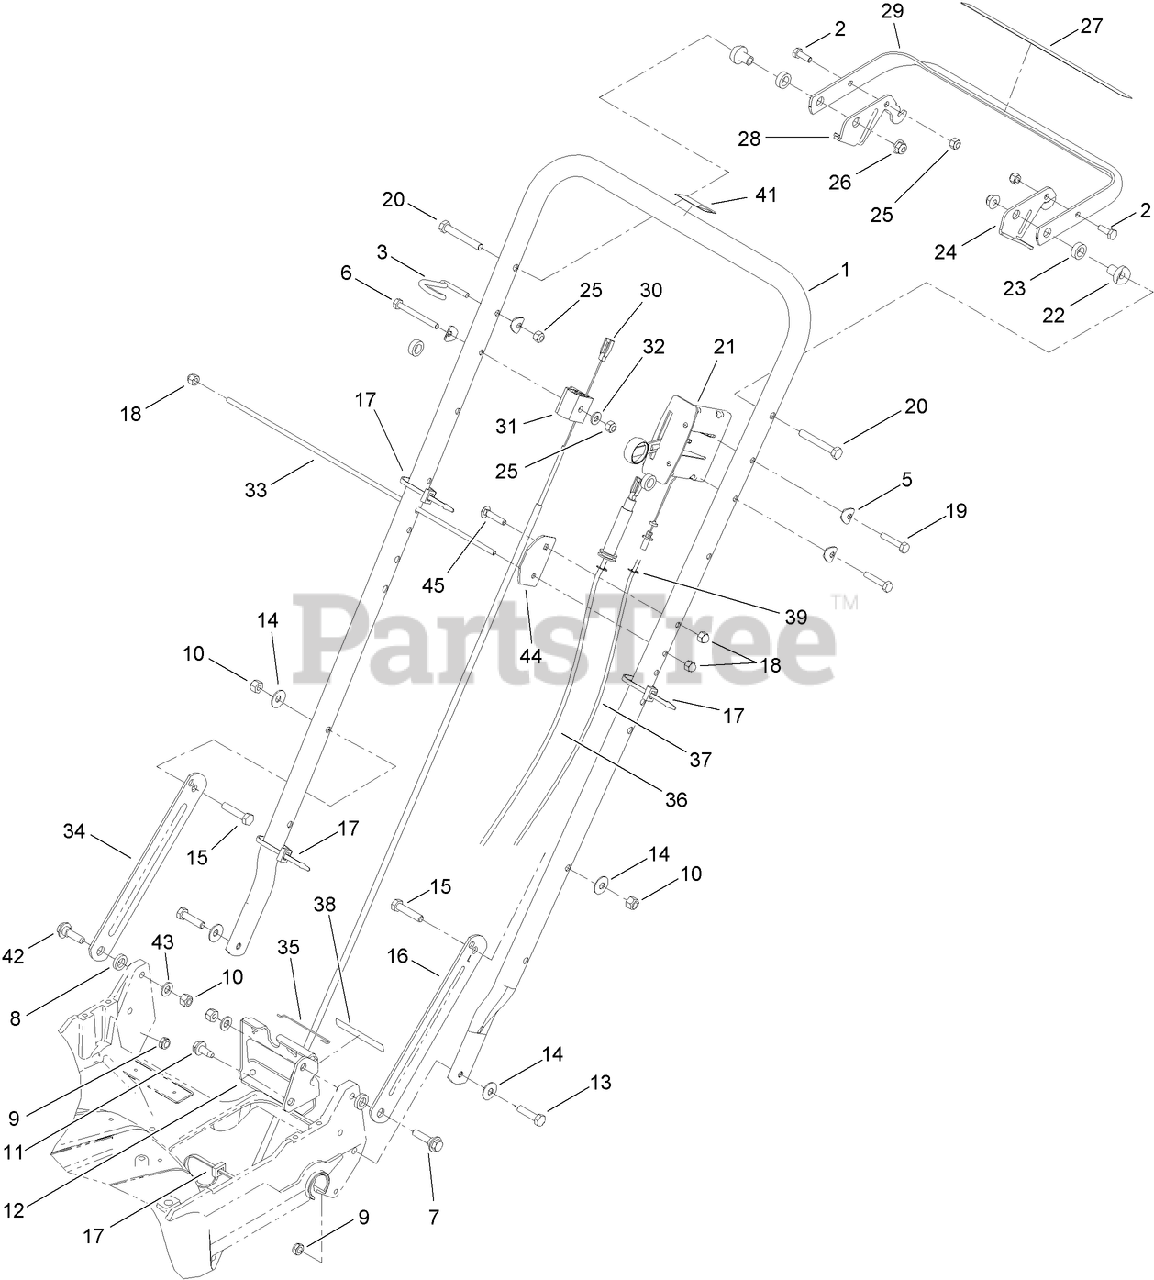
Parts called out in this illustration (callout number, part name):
2	SCREW-HH
3	GUIDE-ROPE
5	WASHER
6	SCREW-HH
7	SCREW-SHOULDER
8	SPACER
9	NUT-LOCK, NI
10	NUT-LOCK, NI
11	SCREW-HWHTF
12	BRACKET-ADJUSTMENT, TRACTION
13	SCREW-HH
14	WASHER-BELLEVILLE
15	SCREW-HH
16	LATCH-HANDLE, LH
17	TIE-CABLE
18	NUT-CAP
19	SCREW-HH
20	SCREW-HH
21	CONTROL-HEAD, THROTTLE
22	SPACER-SUPPORT
23	SPACER-NYLON
24	LEVER-CONTROL
25	NUT-LOCK, NI
26	NUT-HF, NI
27	DECAL-TRACTION
28	LEVER-CONTROL
29	BAR-CONTROL
30	CABLE-CONTROL, BRAKE
31	SUPPORT-CABLE
32	WASHER-FLAT
33	ROD-SUPPORT, BAG
34	LATCH-HANDLE, RH
35	RETAINER-CABLE
36	CABLE-TRACTION
37	CABLE-THROTTLE
38	DECAL-POSITION, GEAR
39	E-RING
41	DECAL-PROTECTION, EAR
42	SCREW-SHOULDER
43	WASHER-PLAIN
44	PLATE-ALIGNING, BAG
45	SCREW-CARR
